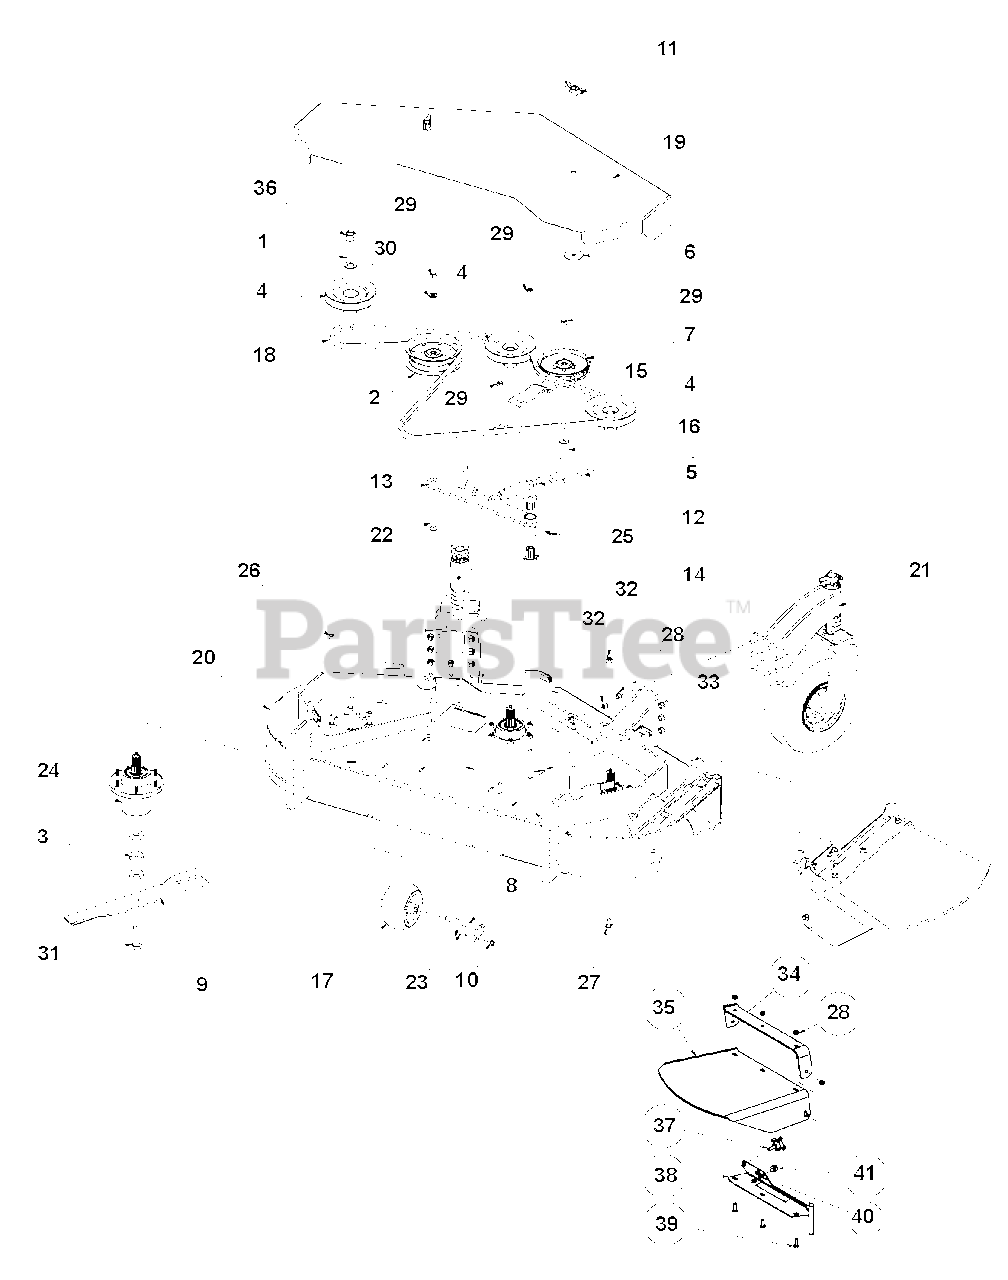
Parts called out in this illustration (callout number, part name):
1	Washer, .75 x 1.312 x .120
2	Pulley, Flat 5.0 x .38 w/Bearing
3	Washer, Blade
4	Pulley, Spline Spindle
5	J-Bolt, 3/8-16 x 4.00 Y
6	Washer, .402 x 2.00 x .055 Fend Y
7	Pulley, Flat 5.00 x .375 W/Bearing
8	Pivot, Retainer Weld
9	Blade, 16.50 Lo-lift
10	Nut-1/4" Flange Prevailing Tor
11	Knob, Locking
12	Spring, Tension
13	Arm, Idler
14	Bearing, Flange M10 x M25 x M27 Fluted
15	Strap, Idler Pulley
17	Wheel, Gage
18	BELT, HB 98.6 EL AMD
19	Shield, Deck w/Decals Gravely
20	Gravely 48" Deck Weldment w/Decals
21	Assembly, Front Wheel Caster (see page 28 for parts)
22	Bolt, Round Head Square Neck .38-16 x 2.25 Grade 5
23	Bolt, 1/4-20 x 1.00 Round Head Square Neck Y
24	Assembly, Spindle Housing
25	Fitting, 1/4-28 Straight Grease Zerk
26	Nut, Hex .38-16
27	Bolt, 3/8-16 x 3/4 Car Grade 5 LNnk
28	Locknut, 3/8-16 Whiz Y
29	Nut, Locking-Flange .375-16
30	Washer, .406 x .813 x .065 FLAT Y
31	Bolt, Hex .62-11X 2.00 Grade 8
32	Locknut, 3/8-16 Nyloc Y
33	Trim 1/4 (1 foot, cut as needed)
34	Strap, Rubber Discharge
35	Shield, Rubber Discharge
36	Locknut, 3/4-16 Crown
37	Knob, 3/8 x 1.25-4 Prong
38	Plate, Discharge 48 FL
39	Bolt, 3/8-16 x 1.00
40	Locknut, 5/16-18 Whiz
41	Bumper, Rubber
